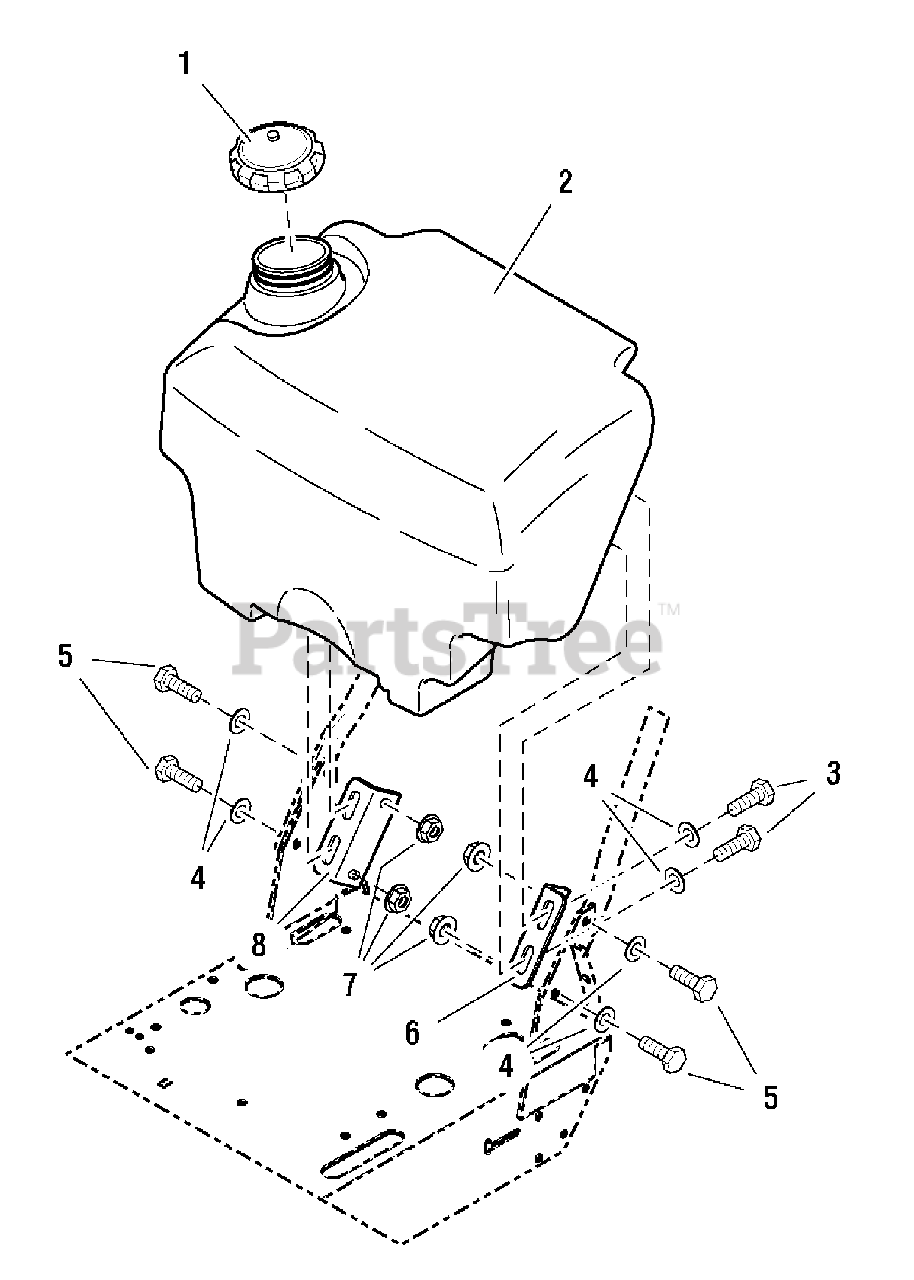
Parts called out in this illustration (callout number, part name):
1	FUEL TANK CAP
3	CAPSCREW, Hex Head, 3/8-16 x 3/4
4	WASHER, 3/8
5	CAPSCREW, Hex Head, 3/8-16 x 1-1/4
6	FUEL TANK MOUNT - LH
7	NUT, Hex Serrated Flange, 3/8-16
8	FUEL TANK MOUNT - RH
